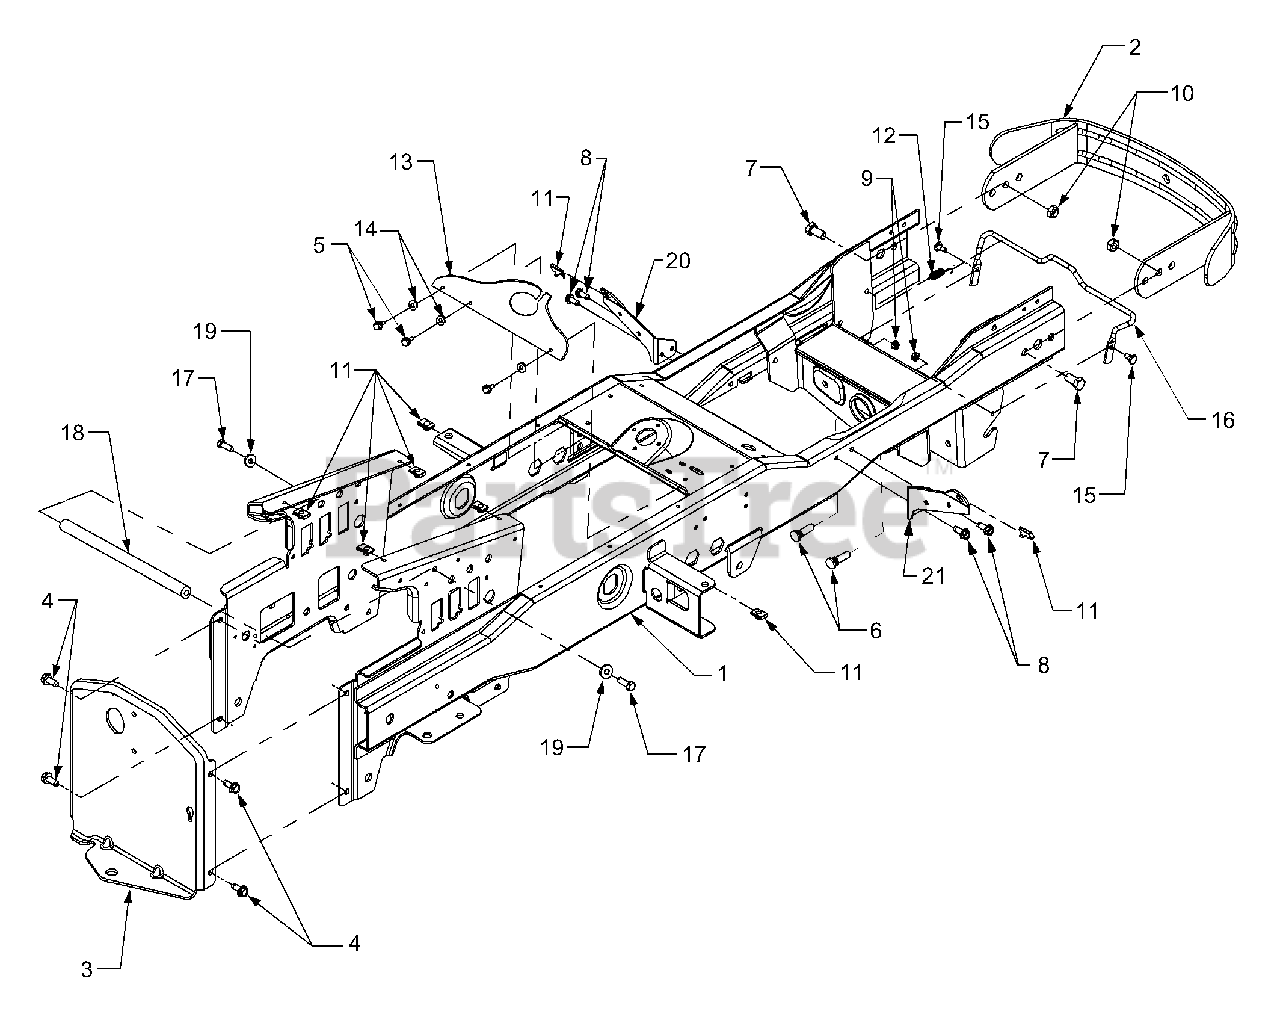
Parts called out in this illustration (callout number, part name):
1	Frame Assembly
2	Bumper, Front
4	Screw, Hex Wash. Hd. Tapp 3/8-16 x .75
5	Screw, Hex Wash. Hd. Tapp 1/4-20 x .5
6	Screw, Round Hd., 3/8-24
7	Screw, Hex Cap 1/2-13 x 1.0 GR5
8	Screw, Hex Wash. Hd. Tapp 5/16-18 x .75
9	Nut, Hex Flange Lock, 1/4-20
10	Nut, Hex Lock, 1/2-13
11	Speed Nut, U-Type, 5/16-18
12	Spring, Extension
13	Flap, Intk.
14	Washer, Flat, .283 x .75 x .030
15	Shoulder Screw, .312 x .18
16	Rod, Front Latch
17	Screw, Hex Cap, 5/16-18 x .875
18	Shaft, Frame Brace
19	Washer, Flat, .344 x .75 x .12
20	Bracket, Running Board LH
21	Bracket, Running Board RH
